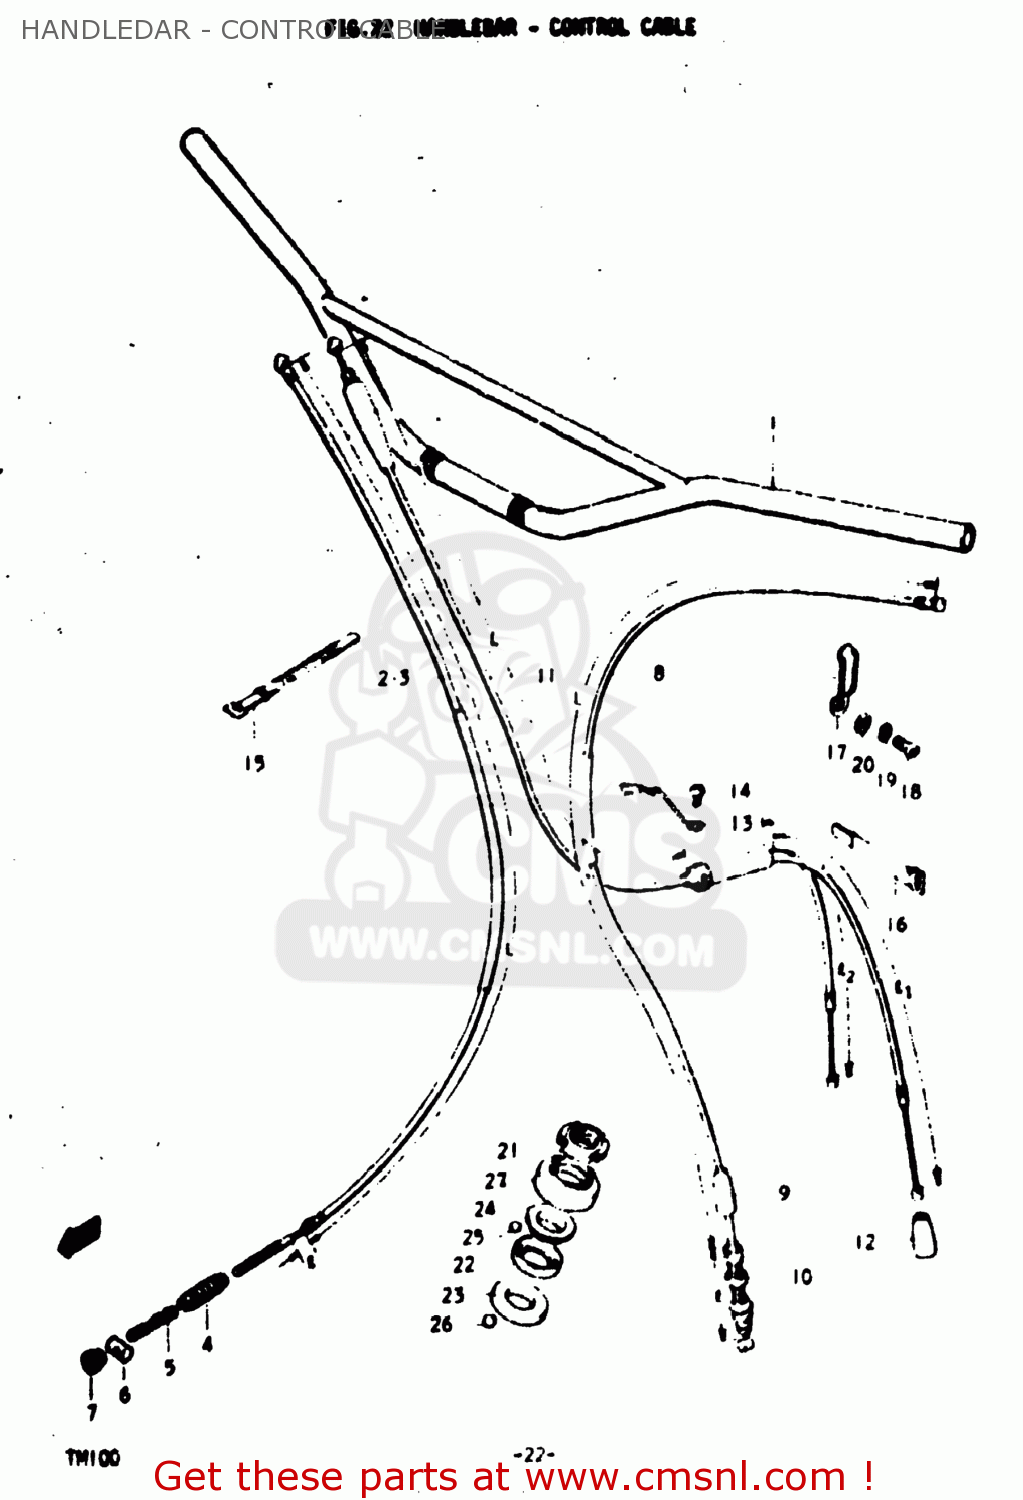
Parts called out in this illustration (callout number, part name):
1	HANDLEBAR
2	CABLE ASSEMBLY,FRONT BRAKE
3	CABLE,FRONT BRAKE
4	SEAL,DUST(7X16X75)
5	SPRING
6	PIN,10X19
7	NUT
8	CABLE ASSEMBLY,CLUTCH
9	SEAL,DUST(7X18X30)
10	NUT
11	CABLE ASSEMBLY,THROTTLE
12	SEAL,DUST(7X18X30)
13	GUIDE,CABLE
14	SCREW
15	CLAMP
16	CLAMP
17	CLAMP
18	SCREW
19	LOCK WASHER
20	WASHER
21	NUT,STEERING STEM(25X44X10)
22	RACE,STEERING INNER UPR
23	LACE,STEERING INNER LWR
24	RACE,STEERING OUTER UPR
25	BALL
26	BALL
27	DUST SEAL,STEERING UPR
